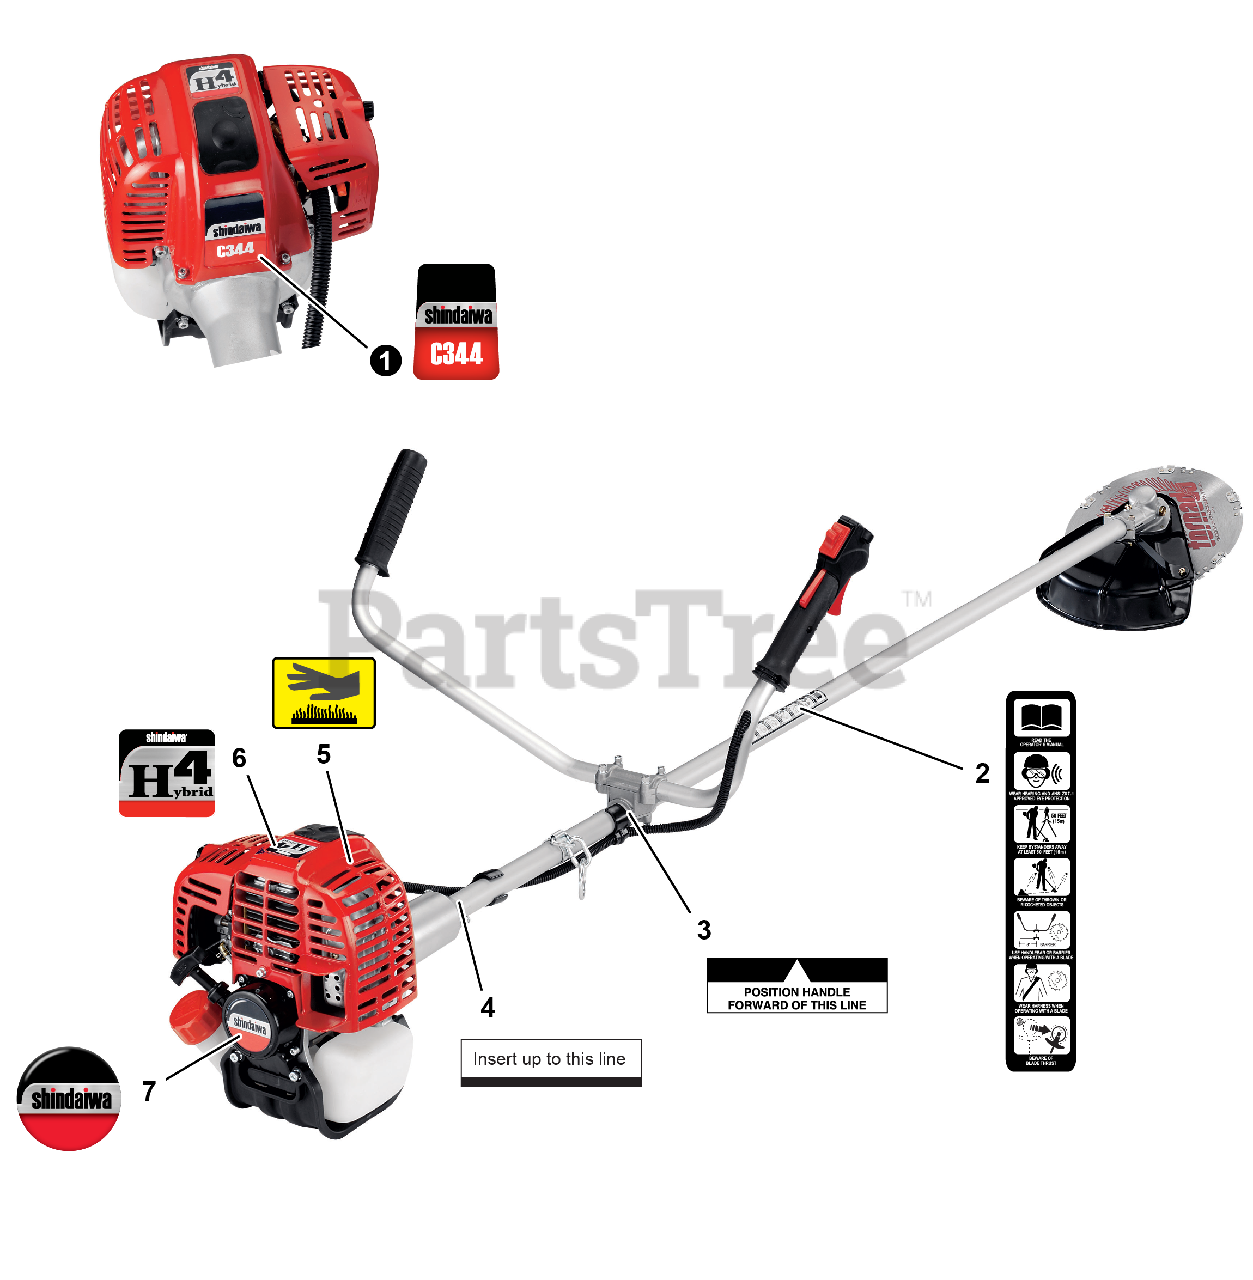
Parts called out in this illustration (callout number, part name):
1	LABEL - MODEL C344
2	LABEL, CAUTION (BLADE CAPABLE)
3	LABEL, HANDLE
4	LABEL - ALIGNMENT
5	LABEL, CAUTION - HOT
6	LABEL, Shindaiwa H4
7	LABEL, SHINDAIWA
